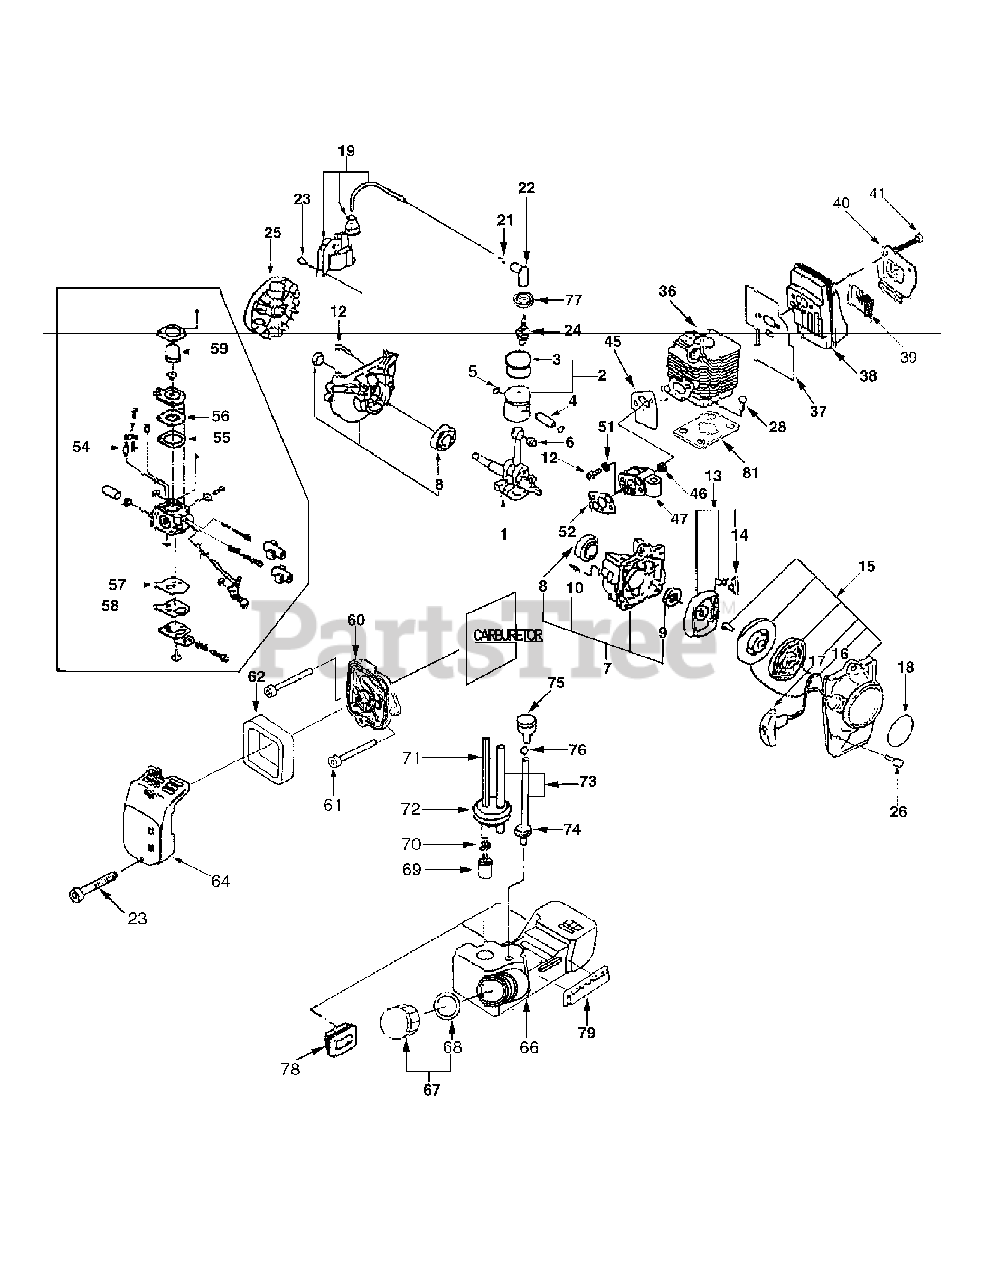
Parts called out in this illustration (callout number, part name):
1	Crankshaft
2	Piston Ass'y
3	Ring, Piston
4	Pin, Piston
5	Clip, Piston Pin
6	Needle, Bearing
7	Crankcase Ass'y
8	Ball Bearing; 6201
9	Oil Seal
10	Dowel Pin
11	Crankcase Ass'y
12	Bolt; M5X25
13	Pulley Ass'y, Starter
15	Recoil Ass'y
16	Rope, Starter
17	Knob,starter
18	Name Plate
19	Coil Ass'y, Ignition
22	Cap, Plug
23	Bolt; M4x20
24	Plug, Spark
25	Flywheel, Magneto
26	Bolt; M5x20
28	Bolt; M5x16
36	Cylinder
37	Gasket, Muffler
38	Muffler, Exhaust
39	Arrester
40	Baffle Plate, Outer
41	Bolt; M5x48
45	Gasket, Insulator
47	Insulator
51	Washer
52	Gasket, Carburetor
53	Carburetor Ass'y
54	Valve, Float
56	Diaphragm, Metering
57	Diaphragm, Pump
60	Case, Air Silencer
61	Bolt; M5x50
64	Case, Cap
66	Tank, Fuel
67	Cap Ass'y, Fuel Tank
69	Filter, Fuel
71	Hose
75	Valve Ass'y, Reversing
79	Rubber
80	Gasket Kit
82	Spring, Spiral
85	Spring, Return
